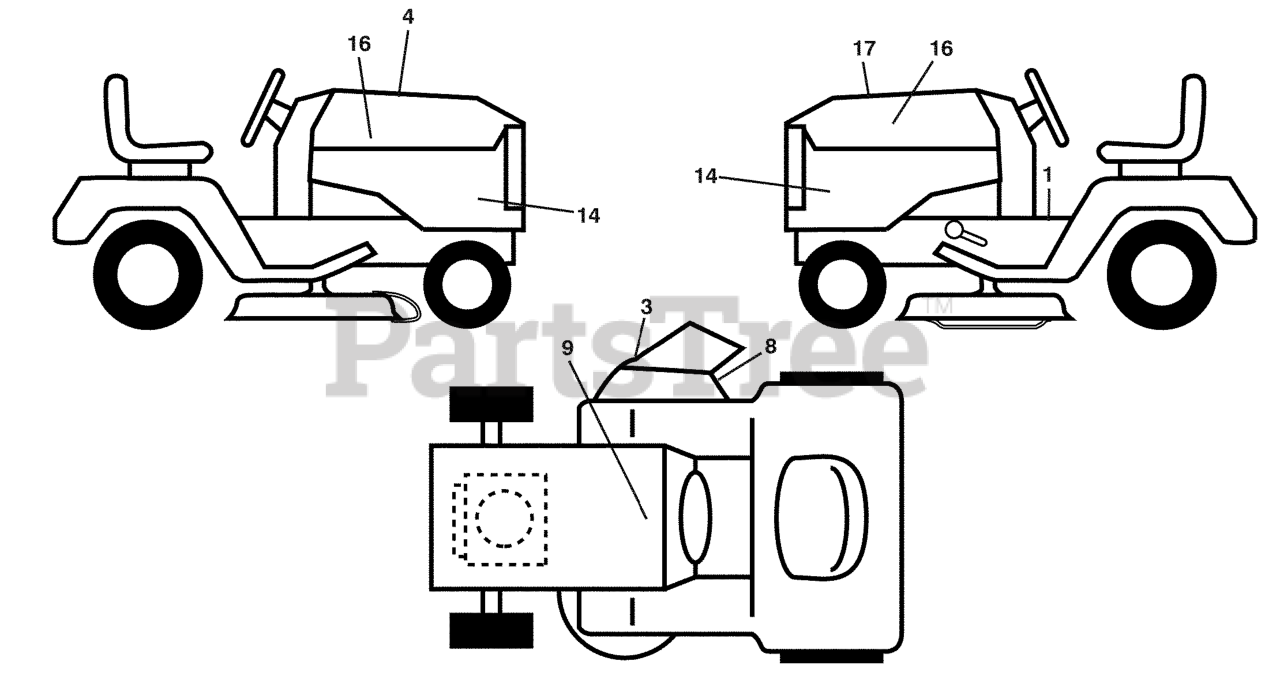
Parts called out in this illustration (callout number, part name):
1	DECAL.FENDER.WARNING.ENG
3	DECAL.WARN.KEEP.HAND.AWAY
4	DECAL.WARNING.CUST.RESP.E85.
8	DECAL.MOWER.SCH.48/54
9	DECAL BTRY SYMBOLS
14	DECAL.PNL.SD.LGT2554.KOHL.
16	DECAL.HOOD.LOGO.ORANGE.HUSQVAR
